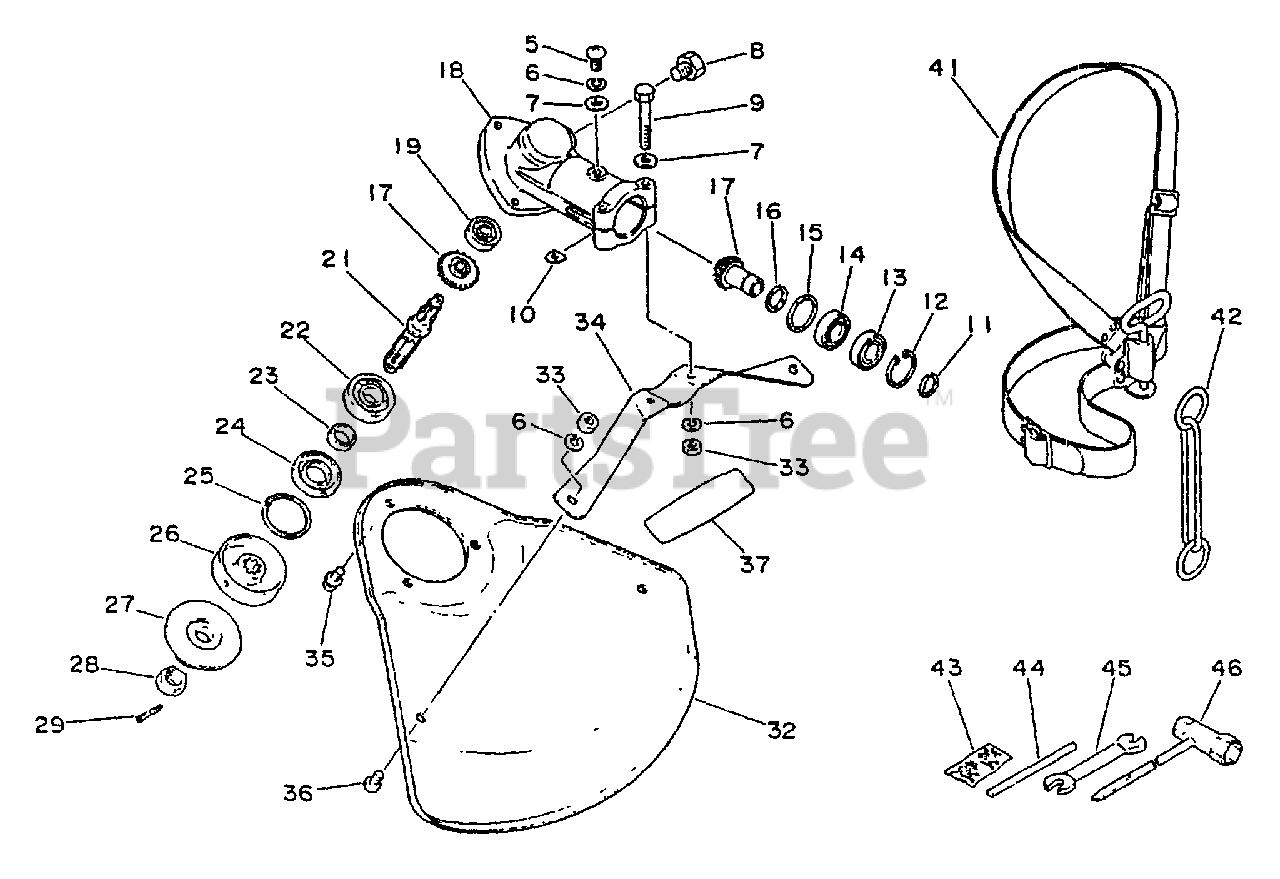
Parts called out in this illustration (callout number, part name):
5	SCREW - 5X10
6	LOCKWASHER - 5
7	WASHER - 5
8	BOLT - 8X8
9	BOLT - 5X35
11	RING, RETAINING - 10
12	RING, RETAINING - 22
13	BEARING, BALL - 6900Z
14	BEARING, BALL - 6900
17	GEAR SET
18	GEAR CASE ASSY
19	BEARING, BALL - 626
21	GEAR - SHAFT
22	BEARING, BALL - 6000
24	SEAL, OIL
25	RING, RETAINING - 26
26	ADAPTOR, BLADE - UPPER
27	ADAPTOR, BLADE - LOWER
28	NUT - 10 -- LEFT HAND
29	PIN, SPLIT - 2X22
32	SHIELD, DEBRIS - METAL
33	WASHER - 5
34	BRACKET, SHIELD
35	SCREW - 5X10
36	SCREW - 5X8
37	LABEL - ECHO
41	SHOULDER STRAP ASSY
43	PIN, SPLIT - 2X22
44	LOCKING TOOL
45	SPANNER - 8X10mm
46	T-WRENCH - 17X19mm
50	LABEL - ECHO
51	LABEL - CAUTION
52	SHIELD, DEBRIS - PLASTIC
53	KNIFE, TRIMMER LINE
54	GUARD
55	SCREW - 5X16
56	PLATE, SHIELD
